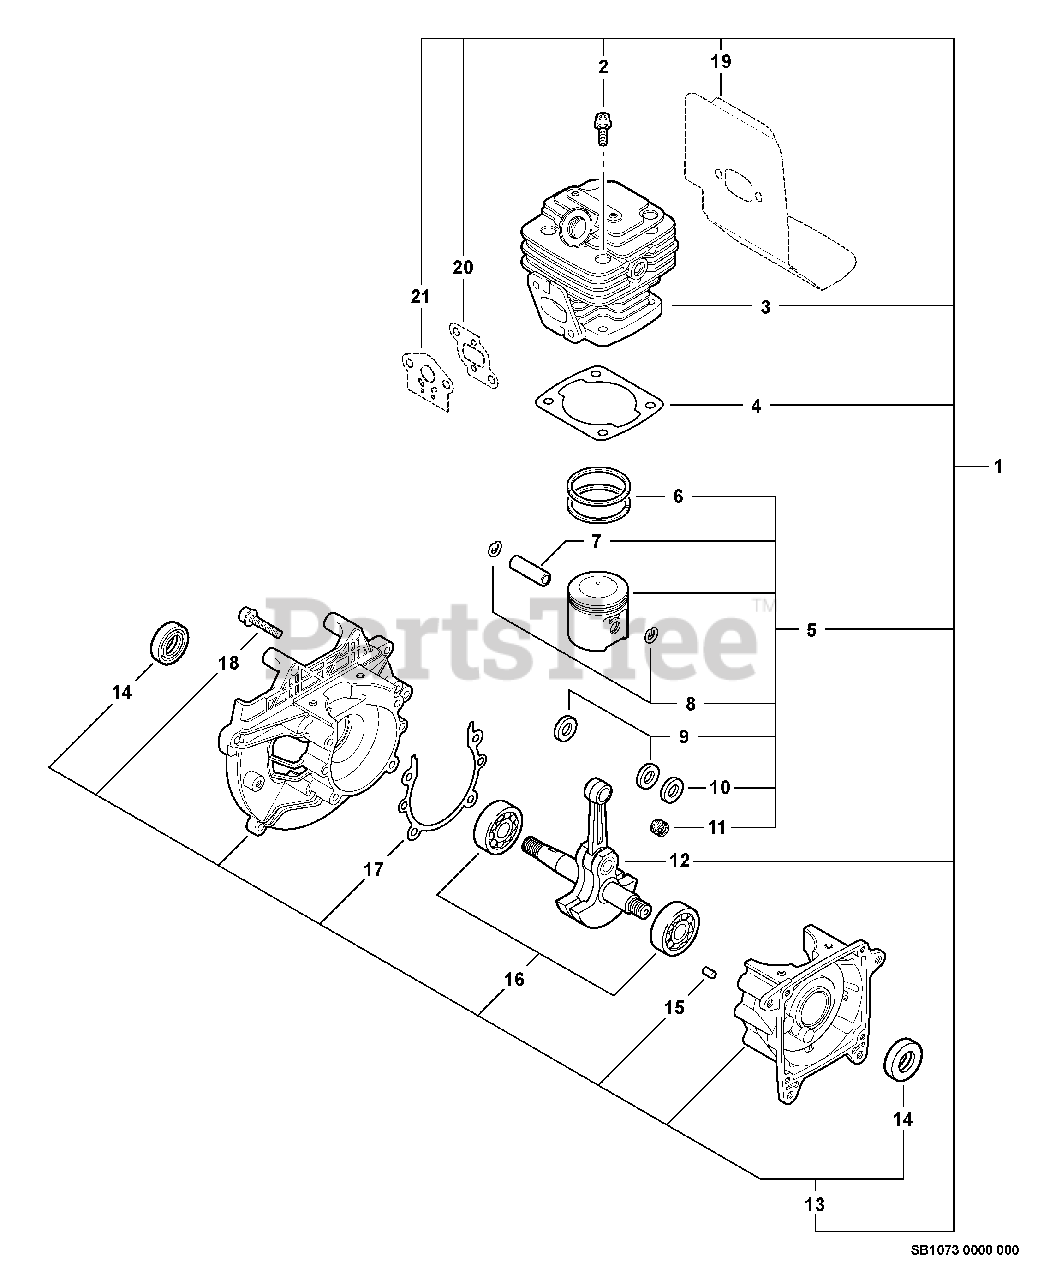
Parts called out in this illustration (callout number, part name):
1	SHORT BLOCK
2	BOLT 5×20
3	CYLINDER
4	GASKET, CYLINDER
5	PISTON KIT
6	RING, PISTON
7	PIN, PISTON
8	RING, SNAP
9	WASHER, THRUST
10	WASHER
11	BEARING, NEEDLE 9
12	CRANKSHAFT ASSY
13	CRANKCASE KIT
14	SEAL, OIL 12
15	PIN, LOCATING 4
16	BEARING, BALL - 6201 C3
17	GASKET, CRANKCASE
18	BOLT 5×30
19	SHIELD, EXHAUST
20	GASKET, INTAKE
21	GASKET, INTAKE
